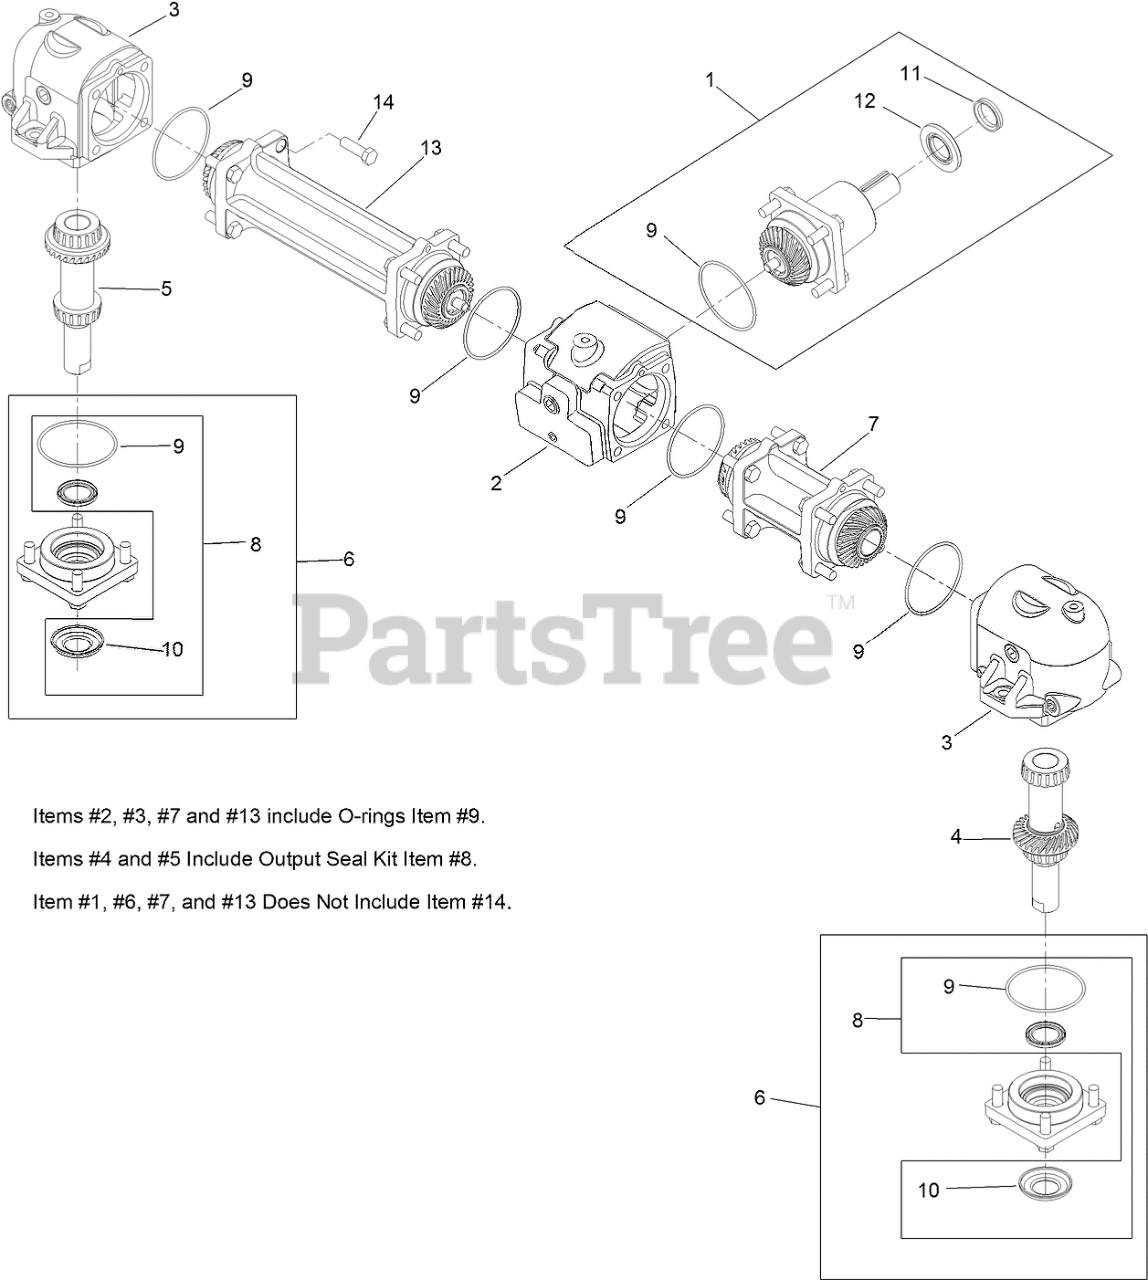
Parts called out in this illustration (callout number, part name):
1	PINION-INPUT
2	HOUSING-CENTER
3	HOUSING-END
4	OUTPUT SHAFT AND GEAR-LH
5	OUTPUT SHAFT AND GEAR-RH
6	CAP-OUTPUT
7	TUBE-CONNECTOR, SHORT
8	OUTPUT SEAL KIT
9	SEAL-O-RING
10	WASHER-CUPPED
11	SEAL-V-RING
12	SEAL-INPUT
13	CONNECTOR-TUBE, LONG
